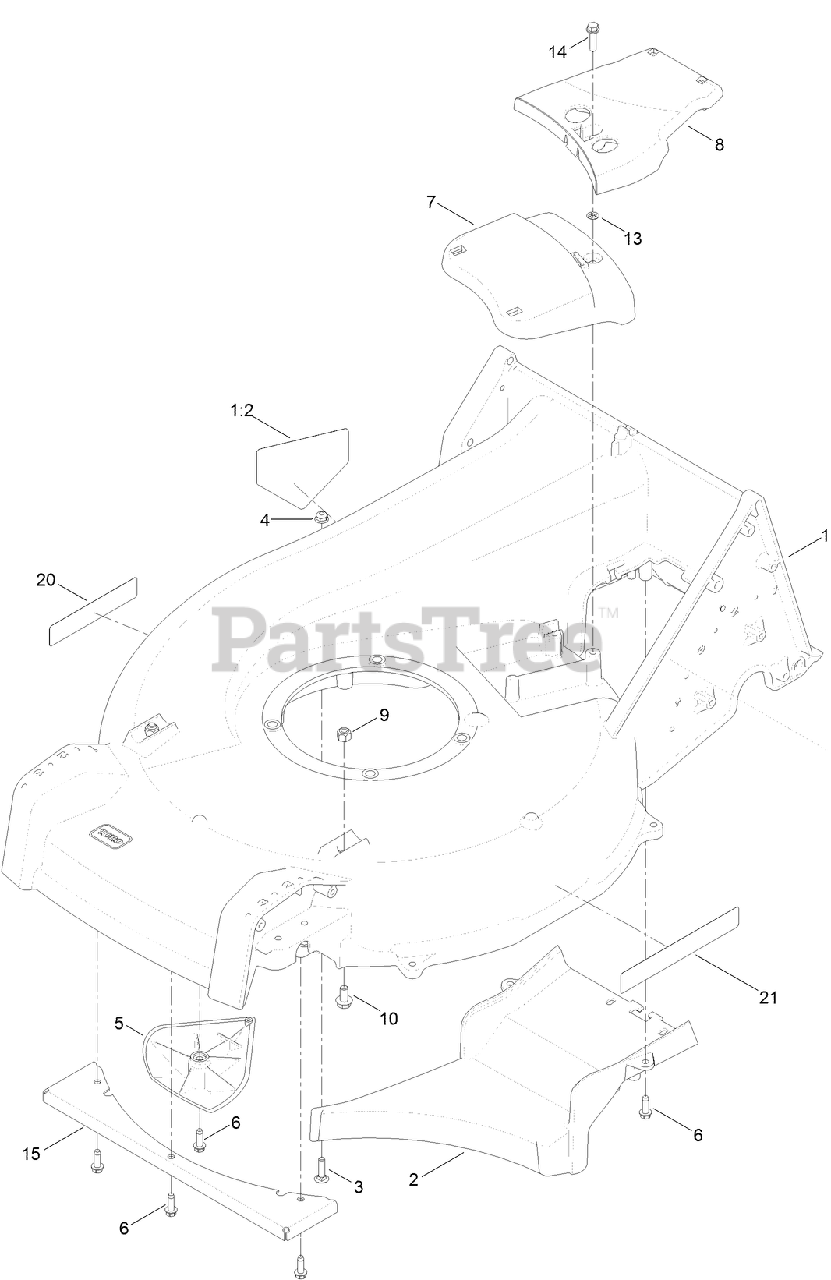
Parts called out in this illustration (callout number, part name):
1	HOUSING ASM
1:2	DECAL-DANGER
2	FLOOR-CHUTE
3	SCREW-CARR
4	NUT-HF
5	KICKER
6	SCREW-HWHTF
7	COVER-BELT, FRONT
8	COVER-BELT, REAR
9	NUT-LOCK, NI
10	SCREW-HHF
13	NUT-RETAINER
14	SCREW-HWHTF
15	GUARD-TOE, FRONT
21	DECAL-RECYCLER
